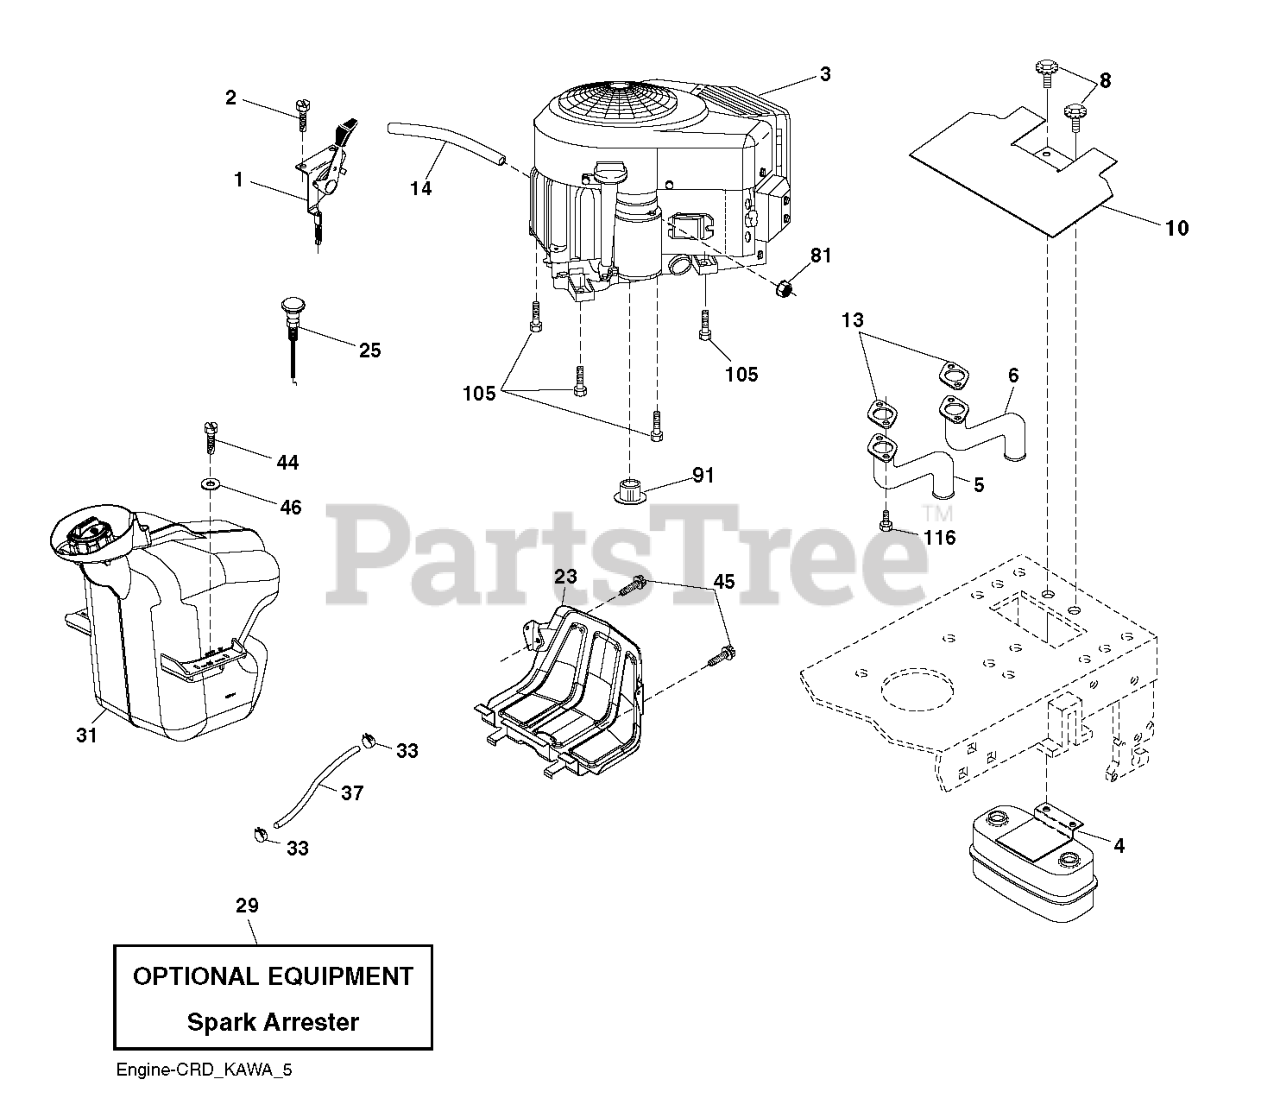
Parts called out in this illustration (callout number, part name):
1	THROTTLE CABLE
2	SCREW.#10 X 0.750.BOS
4	MUFFLER.TWIN.CYL.LOW.TONE
5	TUBE.EXHAUST.LH.FR961/FR730
6	TUBE.EXHAUST.RH.FR961/FR730
8	BOLT.5/16-18UNCX3/4 W/SEMS.BLK
10	SHIELD.HEAT.MUFFLER
14	TUBE, DRAIN OIL ASM.
23	SHIELD.BROWNING.PNT.GT.V2
25	CONTROL.CHOKE.ERGO.PUSH-IN.BLA
29	KIT.SPARK ARRESTOR 794945 B&S
33	HOSE CLAMP
37	LINE.FUEL.20
44	SCREW HEXWSHR 1/4-20X3/4
45	SCREW, 3/8-16X3/4
81	NUT
91	BUSHING.1.375OD
105	SCREW 3/8-16X1
116	NUT.HEX.FLANGE.TOPLOCK
